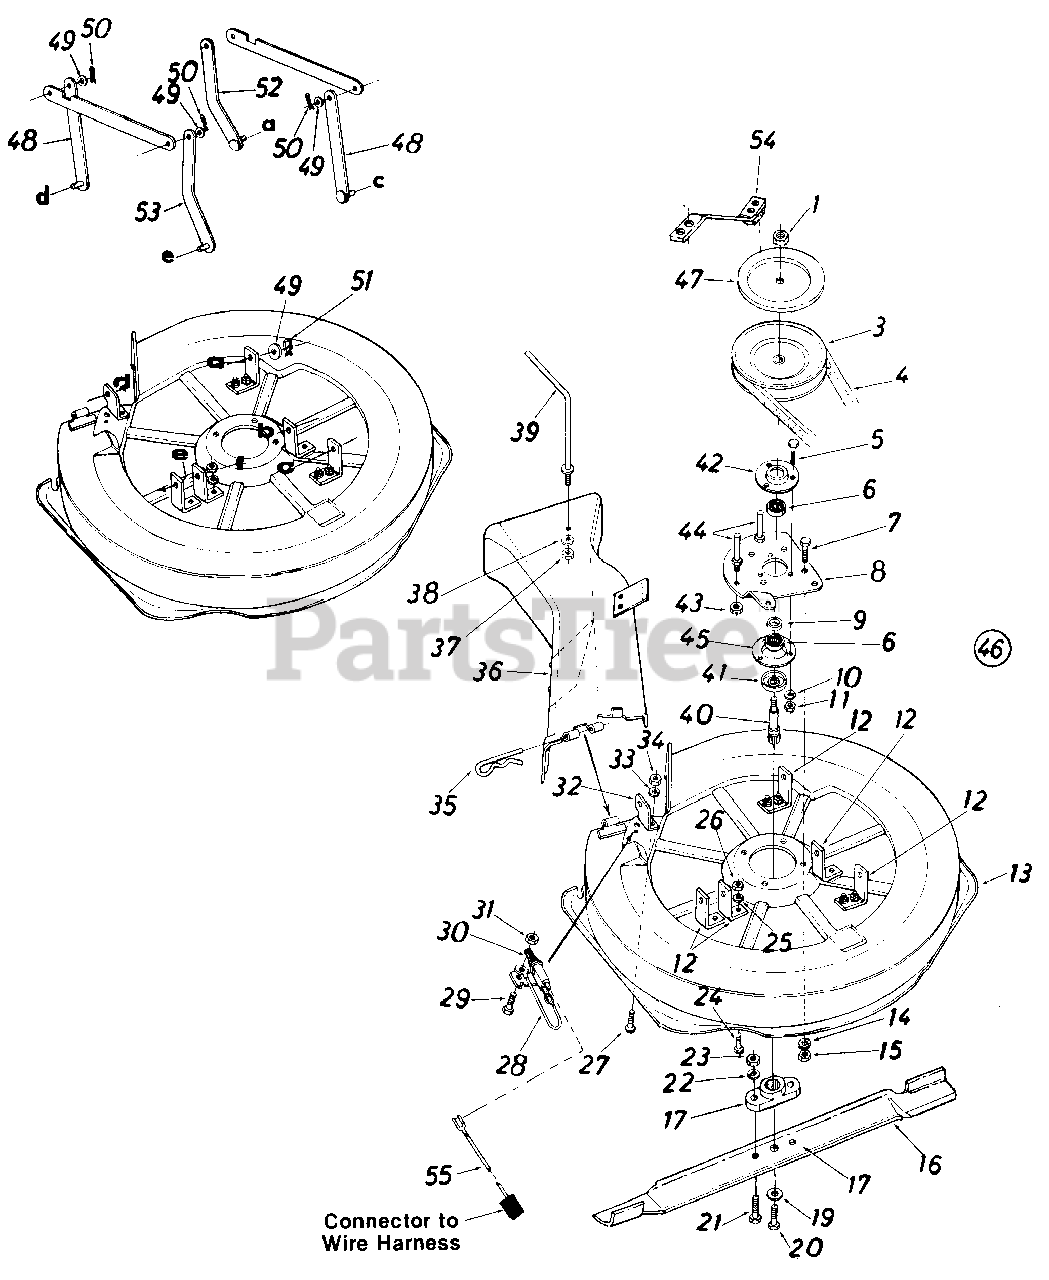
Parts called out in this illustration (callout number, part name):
1	Hex Jam Nut 5/8-18 Thd.
5	Hex Bolt 5/16-18 x 1.00" Lg.*
6	Ball Brg..787" I.D.
7	Hex Bolt 5/16-18 x .75" Lg.
8	Spindle Mtg. Plate
9	Spacer
10	L-Wash. 5/16" I.D.
11	Hex Nut 5/16-18 Thd.
12	Hanger Bracket
15	Hex Nut 5/16-18 Thd.
16	30" High Lift Blade-R.H.
17	Blade AdaPter
19	Bell-Wash. .39" I.D. x 1.38"O.D.
20	Hex Bolt 3/8-24 x 1.00" Lg.
21	Hex Bolt 5/16-24 x 1.00" Lg.
22	L-Wash. 5/16" I.D.
23	Hex Nut 5/16-24 Thd.
24	Hex Bolt 5/16-18 x .75" Lg.
25	L-Wash. 5/16" I.D.
26	Hex Nut 5/16-18 Thd.*
27	Truss Mach. Scr. 5/16-18 x .75" Lg.
28	Electrical Wire
29	Hex Bolt 1/4-20 x .50" Lg.
30	Safety Switch
31	Hex Nut 1/4-20 Thd.
32	Angle Hanger Brkt.
33	L-Wash. 5/16" I.D.
34	Hex Nut 5/16-18 Thd.
35	Internal Cotter Pin
36	R.D. Chute Deflector
37	Hex L-Nut 5/16-18 Thd.
38	L-Wash. .32" I.D. x .62" O.D.
39	90ø Rod 5/16-18 Thd.
40	Blade Spindle x 5.20
41	Bearing Shield
42	Open Brg. Housing 1.85" I .D.
43	Hex Jam Nut 3/8-16 Thd.
44	Stud 3/8-16 x 3.0" Lg.
45	Brg. Housing 1.85" I.D.
46	30" R.D. Deck Ass'y. Comp.
47	Brake Disc
48	Link Deck Hanger Ass'y
49	Fl-Wash. .40" I.D. x .88" O.D.
50	Inter. Cotter Pin 3/8" Dia.
51	Inter. Cotter Pin .50" Dia.
54	Blade Brake Assy
55	Wire Lead
